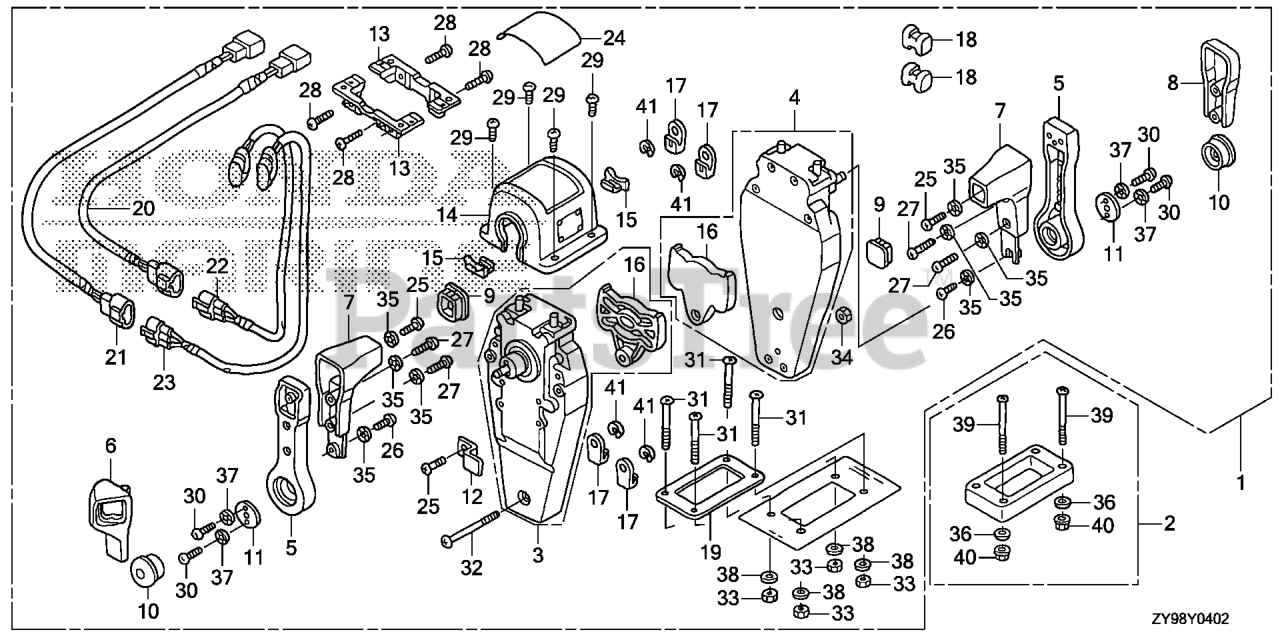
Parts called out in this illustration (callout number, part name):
1	BOX KIT
2	SPACER KIT, REMOTE CONTROL BOX (TOP MOUNT DUAL)
3	HOUSING ASSY., L. (INNER) (TOP MOUNT)
4	HOUSING ASSY., R. (INNER) (TOP MOUNT)
5	HANDLE, REMOTE CONTROL
6	COVER, L. GRIP
7	GRIP, REMOTE CONTROL HANDLE
8	COVER, DUAL GRIP
9	CAP, GRIP
10	BUTTON, THROTTLE
11	PLATE, HANDLE
12	PLATE, CABLE CLAMP
13	BRACKET, REMOTE CONTROL HOUSING
14	HOUSING, DUAL REMOTE CONTROL BOX
15	HOUSING, LEAD
16	PLATE, DWELL
17	TERMINAL, CABLE
18	SPACER, CABLE CLAMP
19	GASKET, DUAL
20	SUB-HARNESS ASSY., POWER TRIM-TILT (A)
21	SUB-HARNESS ASSY., POWER TRIM-TILT (B)
22	SWITCH ASSY., POWER TRIM-TILT (A)
23	SWITCH ASSY., POWER TRIM-TILT
24	MARK, REMOTE CONTROL (DUAL)
25	SCREW, PAN (5X16)
26	SCREW, PAN (5X10)
27	SCREW, PAN (5X20)
28	SCREW, PAN (5X18)
29	SCREW, PAN (4X10)
30	SCREW, PAN (6X18)
31	SCREW, PAN (5X40)
32	SCREW, PAN (5X55)
33	NUT, HEX. (5MM)
34	NUT, HEX. (5MM)
35	WASHER, LOCK (5MM)
36	WASHER, PLAIN (5MM)
37	WASHER, LOCK (6MM)
38	WASHER, PLAIN (5MM)
39	SCREW, PAN (5X65)
40	NUT, HEX. (5MM)
41	E-RING (6MM)
